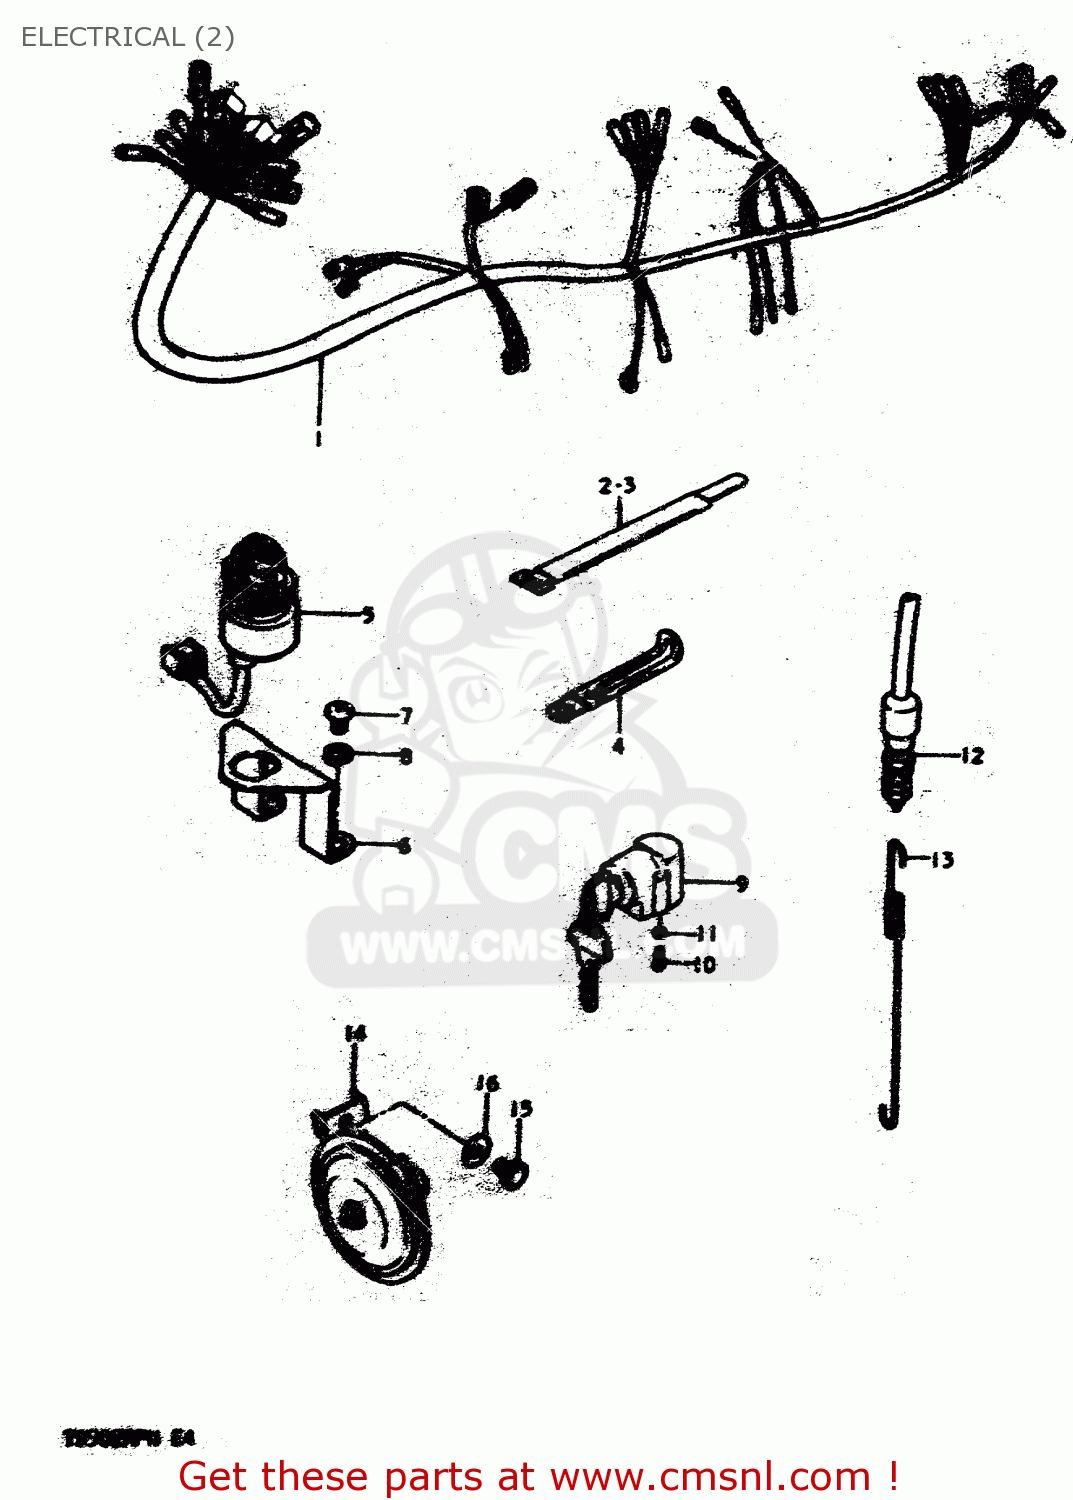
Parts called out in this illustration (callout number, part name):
1	WIRING HARNESS
2	CLAMP
3	CLAMP
4	CLAMP
5	SWITCH ASSY, IGNITION
6	BRACKET, IGNITION SWITCH
7	SCREW
8	LOCK WASHER
9	LOCK ASSEMBLY,STEERING
10	SCREW
11	LOCK WASHER
12	SWITCH ASSEMBLY,STOP LAMP
13	SPRING
14	HORN
15	BOLT
16	WASHER
